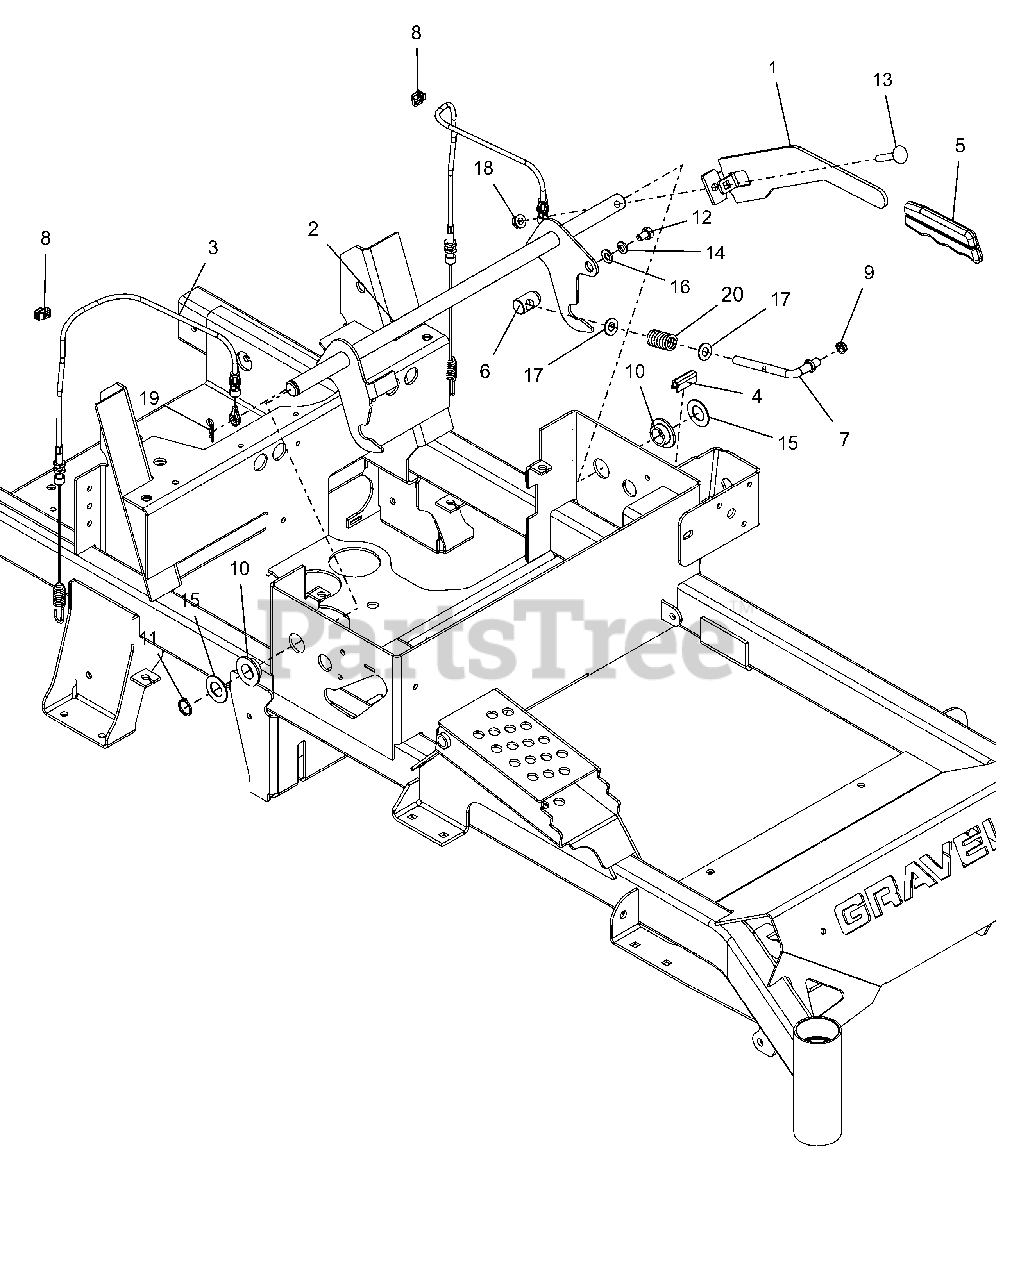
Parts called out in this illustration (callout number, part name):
1	PT/PT100 BRAKE HANDLE - BLK
2	WLDMT, COMPACT PRO BRAKE LEVER
3	CABLE, BRAKE ACTUATING
4	STRIP, COWL
5	GRIP, PARKING BRAKE (YELLOW)
6	TRUNNION, BRAKE
7	LINK, OVER CENTER BRAKE
8	CLIP SOLAR
9	BUSHING, POLYLINER-.38 SNAPIN
10	BSHG-FLG .762X1.48X.44 NYL
11	RG-RTNG-EXT .689X.078
12	BLT, HEX .31-18X.50 GR5 ZCC
13	BLT,RHSSN-.312X1.75 G5 RIE5230
14	WSHR,LK-REG .312X.078 ZCC
15	WSHR, FLT .755X1.375X.062 ZCC
16	WSHR,FLT .344X.688X.065 ZCC
17	WSHR-FL-STL 0.406X0.812X0.055 HRD
18	NUT,LK-CTR-FLG .31-18 GF ZCC
19	PIN, HAIR #213 .08X1.19 ZCC
20	SG-COMP .125X.781X1.250
